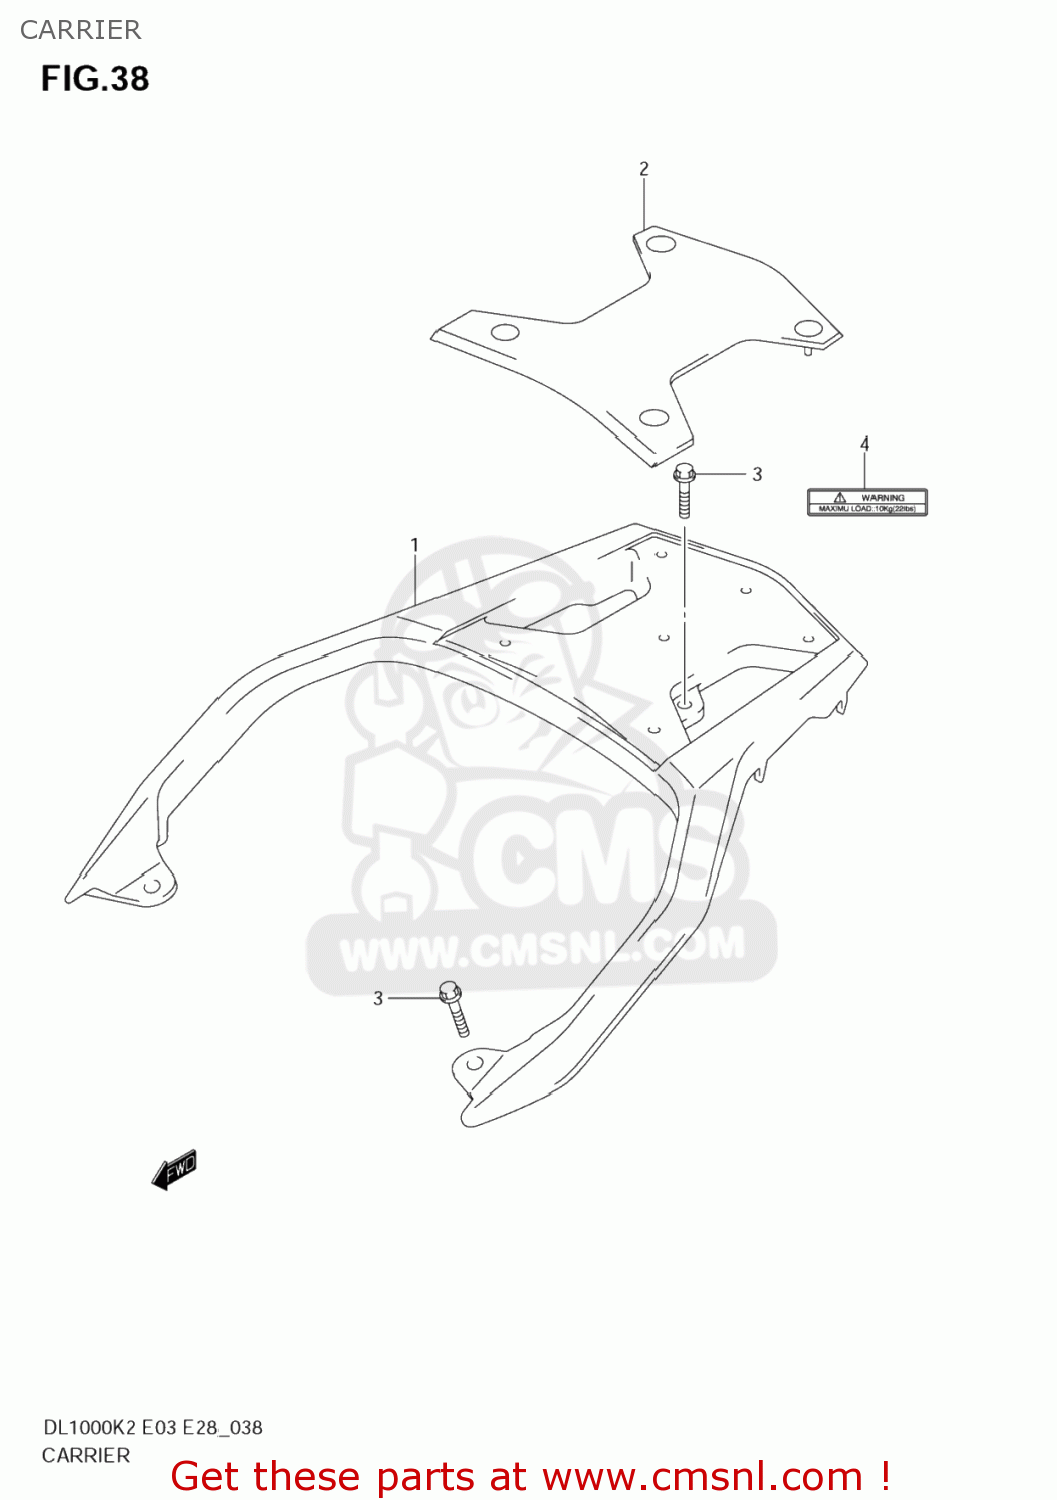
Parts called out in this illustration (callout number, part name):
1	CARRIER,SPORT
2	MAT,SPORT CARRIER
3	BOLT(8X30)
4	LABEL,CARRIER
